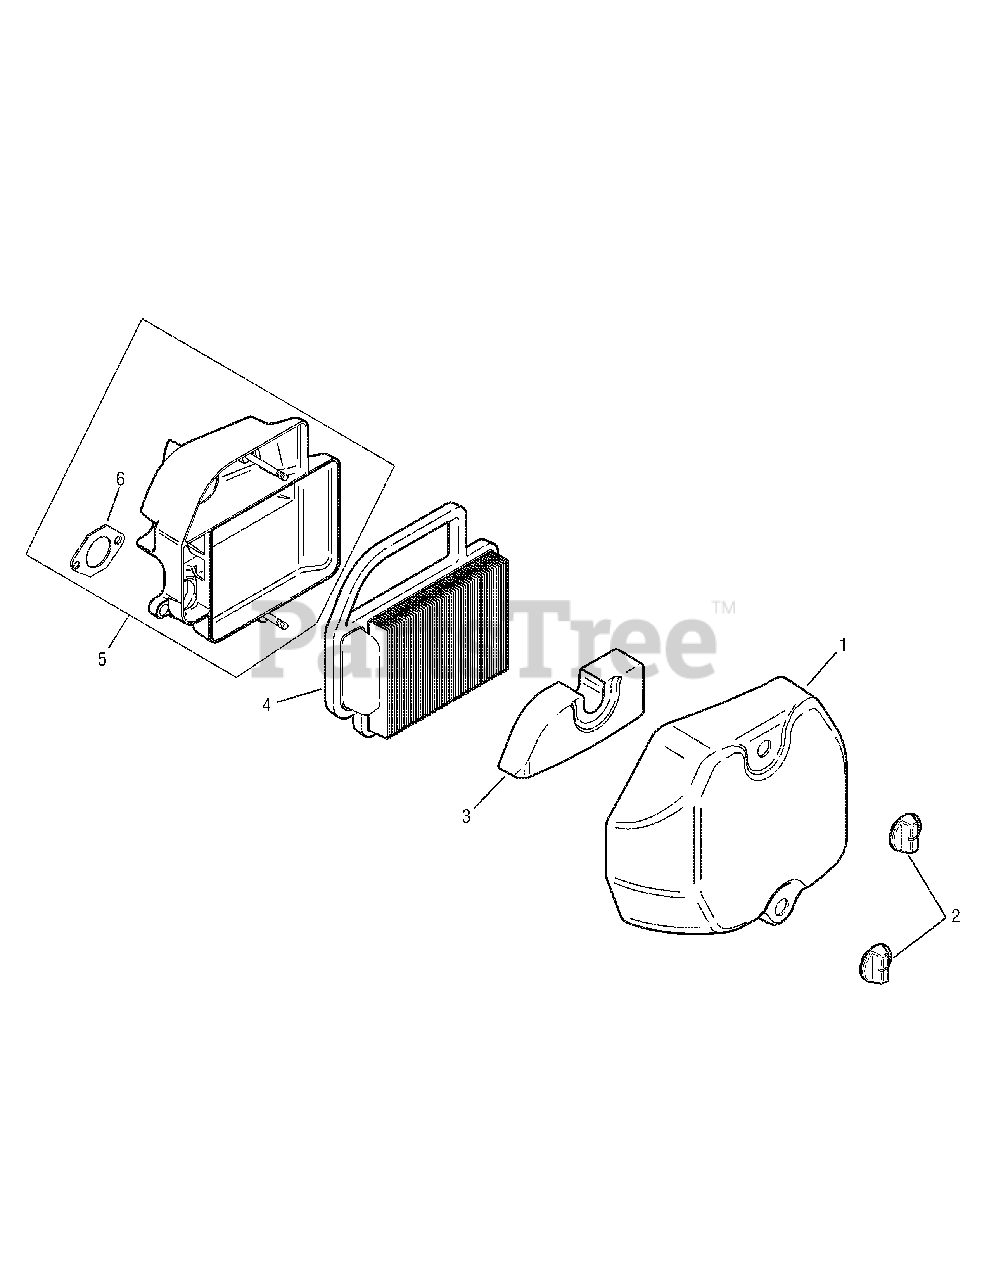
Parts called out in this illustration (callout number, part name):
1	Cover, air cleaner
3	Element, precleaner
4	Element, air cleaner
5	Kit, air cleaner base
6	Gasket, air cleaner base
